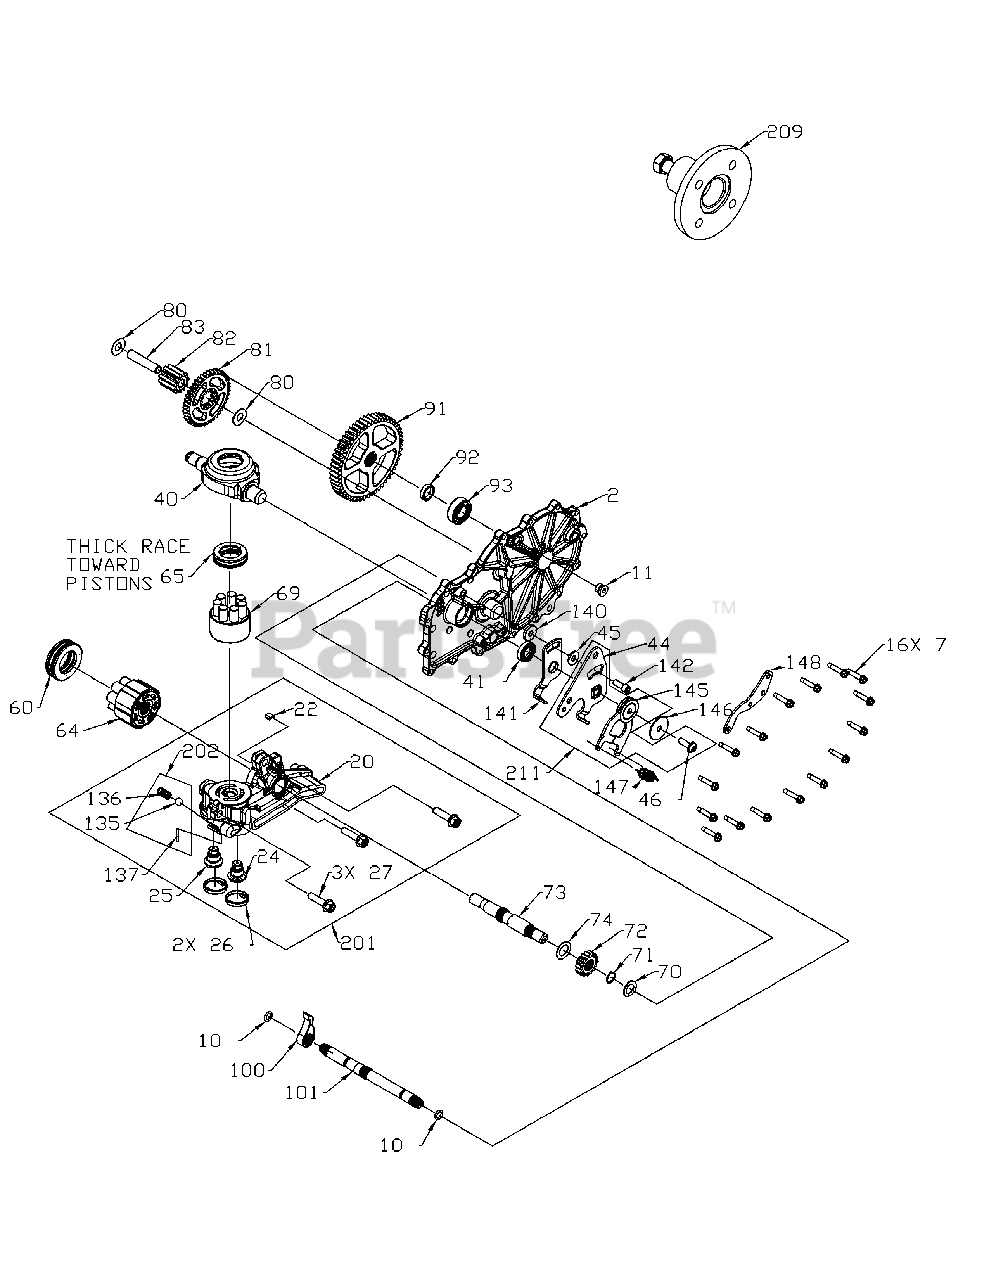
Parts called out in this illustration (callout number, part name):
1	Kit, Housing Main RH Chrg
1	Housing, Main RH Chrg
1	Bushing .624 x .719 x .562
1	Brg, Jrnl .86 x .98 x .79
1	Pin .25 x .375
2	Kit, Cover Side RH Cntl
2	Cover, Side RH Cntl
2	Bushing .624 x .719 x .562
2	Brg, Jrnl .86 x .98 x .79
7	HFHCS 1/4-20 x 1.25''
10	O-Ring 111.103 x .424
11	Plug 9/16/18 (Metal)
20	Center Section, RH Chrg
22	Plate, Bypass
23	Filter, Oil
24	Shock Valve
25	Shock Valve
26	Seal, Plug 1.250 x .250
27	HFHCS 3/8-16 x 1.5 (Patch)
30	Seal, Lip .375 x .75 x .25
31	Ring, Ret .375 External
32	Rod, Bypass
33	Ring, Ret .750 Internal
34	Arm, Bypass
35	Ring, Rtng .375 Ext
40	Trunnion, Swashplate
41	Seal, Lip 18 x 32 x 7
44	Arm, Control
45	Washer .34 x .88 x .06
46	TWHCS 5/16-24 x 1.00 (Patch)
52	Shaft, Input
53	Brg, Ball 17 x 40 x 12 Open 6203
54	Ring, Ret Wire .561 ID
55	Washer 1.23 x 1.56 x .04
56	Seal, Lip 17 x 40 x 7
57	Ring, Ret 2.06 Internal
60	Bearing, Thrust
64	Cylinder Block Assembly 16cc
65	Bearing, Thrust Ball 30 x 52 x 13
69	Block 7 Piston Assembly
70	Washer .63 x 1.0 x .05
71	Ring, Ret 62 External
72	Gear, 16T
73	Shaft, Motor
74	Washer .72 x 1.16 x .04
80	Washer .5 x 1.0 x .03
81	Gear, 43T
82	Gear, 11T
83	Jack Shaft (Pin)
90	Ring, Ret 2.06 Internal
91	Gear, 54T
92	Spacer, .750 x 1.000 x .257
93	Bearing Ball .75 x 40 x 12
94	Shaft, Axle
95	Bearing Ball 1.0 x 52 x 15 Open 6205M
96	Seal, Lip TC4 (Gray)
97	Hub, 4 Stud (3.56 Taper)
99	Nut, Hex Lock 3/4-16
100	Pawl, Brake
101	Shaft, Brake
102	Handle, Brake
103	Clip, Retaining
105	HFHCS 1/4-20 x .75
106	Guard, Filter - RH
109	Spacer, .91 x 1.02 x .625
111	Fitting, Str 9/16-18 SAE .5 Barb
120	Fan, 7'', 10 Blade
121	Pulley 4.5 Inch
122	Nut, Hex Lock 1/2-20 Nylon
123	HFHCS 1/4-20 x .75
130	Tube, Connecting
131	Gerotor Assembly (1.6 cc/rev)
132	O-Ring, -137, 0.103 x 2.050
133	Cover, Charge Pump
134	HFHCS 1/4-20 x .75
135	Ball, Steel 7/16''
136	Spring relief .42 x .250
137	Pin, Spring .125 x .875
140	Spacer, .320 x 1.005 x .179
141	Arm, Neutral Right
142	SHCS 5/16-24 x 1 (Patch)
145	Assembly, RTN
146	Washer, .343 x 1.500 x .062
147	Spring, Extension .57 x 2''
148	Bracket Damper
200	Kit, Seal
201	Kit, Center Section, RH Chrg
202	Kit, Chrg Relief
203	Kit, Charge
206	Kit, Hub 4 Bolt
207	Kit, Fan/ Pulley
209	Hub Puller, 4 Bolt
210	Kit, Input Shaft
211	Kit, RTN Bidirectional RH
212	Kit, Axle Shaft
